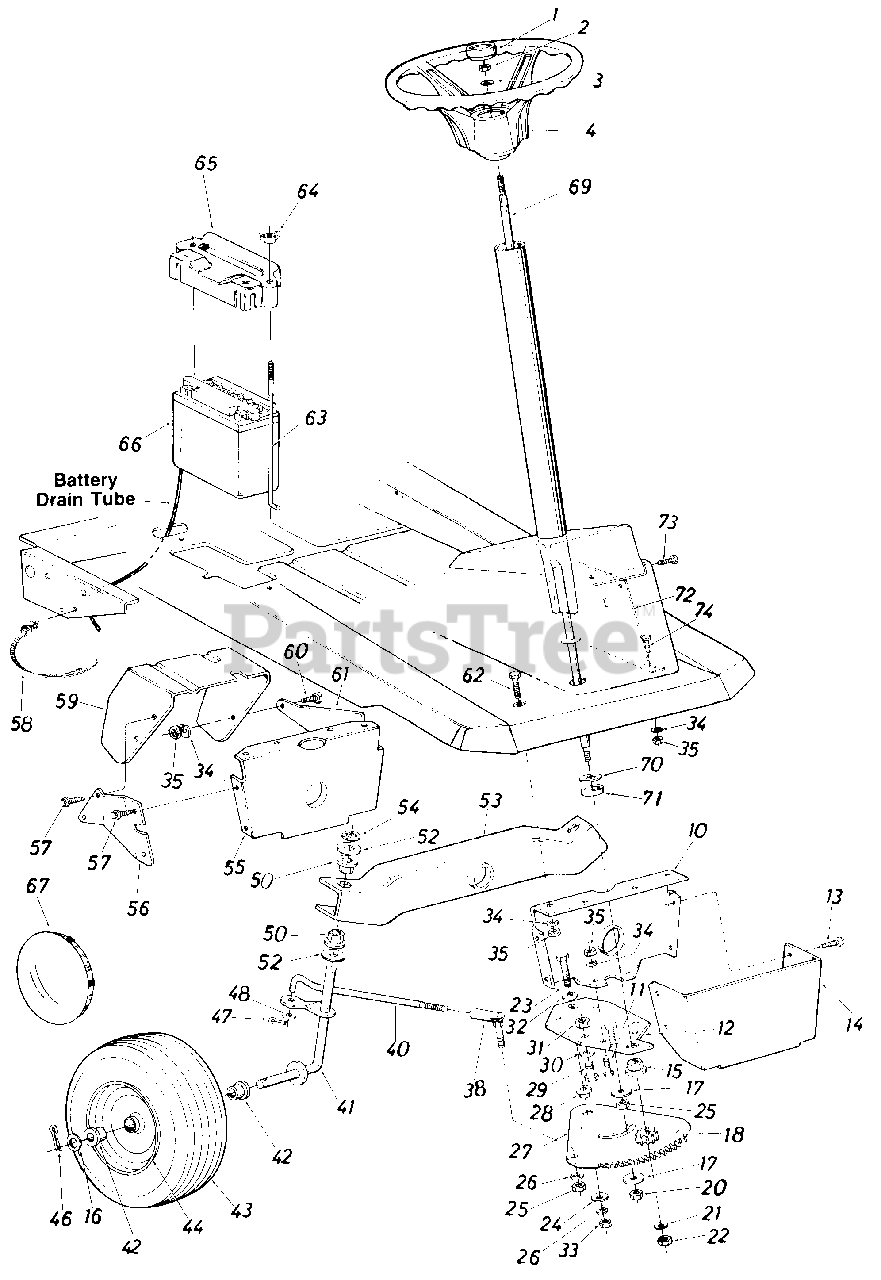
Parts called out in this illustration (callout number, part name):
1	Steering Wheel Cap
2	Hex L-Nut 5/16-24 Thd.
3	Bell-Wash. .345" I.D. x .88" O.D
4	Steering Wheel Ass'y.
10	Pivot Bar Bracket
11	Hex Bolt 5/16-18 x .75" Lg.
12	Steering Gear Support Brkt.
13	Hex Wash. Hd. AB-Tap Scr. 1/4 x.62" Lg.
16	Fl-Wash. .64" I.D. x 1.5" O.D.
17	Fl-Washer 3/8" I.D. x 1.37" O.D
18	Steering Pinion Gear
20	Hex L-Nut 3/8-24
21	Fl-Wash. .34" I.D. x .68" O.D.
22	Hex L-Nut 5/16-24 Thd.
23	Hex Bolt 3/8-24 x 1.5" Lg. (Grade 5)
24	Fl-Wash. .385" I.D. x 1.38"
25	Hex Nut 3/8-24 Thd.
26	L-Wash. 3/8" I.D.*
27	Steering Gear Segment
28	Shoulder Spacer .622" Dia. x .218
29	Hex Bolt (Nylon) 1/2-13 x .75"
30	Fl-Wash. .530" I.D. x .930"
31	Hex Nut 1/2-13 Thd.*
32	Bell-Wash. .385" I.D. x .88"
33	Hex Nut 3/8-24 Thd.
34	L-Wash. 5/16" I.D.
35	Hex Nut 5/16-18 Thd.*
38	Ball Joint Ass'y. 3/8-24 Thd.
40	Steering Tie Rod
41	Front Axle Ass'y.-R.H.
42	Flange Bearing .632" I.D.
43	Wheel Ass"y. Comp. (11 x 4.0)
44	Rim Only (11 x 4.0)
46	Cotter Pin 1/8" Dia. x 1.25"*
47	Cotter Pin 1/8" Dia. x 1.00"*
48	Fl-Wash. .385" I.D. x .87"
50	Hex Flange Bearing
52	Fl-Wash. .635" I.D. x 1.12"
53	Pivot Bar Ass'y.
54	Speed Nut 5/8" I.D.
55	Pivot Bar Bracket
56	Bracket Reinforcement-R.H.
57	Hex Wash. Hd. AB-Tap Scr. 1/4 x .62" Lg.
58	Cable Tie
59	Clutch-Brake Pedal Ass'y.
60	Hex Bolt 5/16-18 x .75" Lg.*
63	Battery Hold Down Rod
64	Wing Nut Solid 1/4-20 Thd.
65	Battery Hold Down Cover
66	12V Battery
67	Chrome Hub Cap
69	Steering Shaft Ass'y.
70	Fl-Wash. .62" I.D. x 1.25" O.D.
71	Spacer (Plastic)
74	Hex Bolt 5/16-18 x 2.00" Lg.
